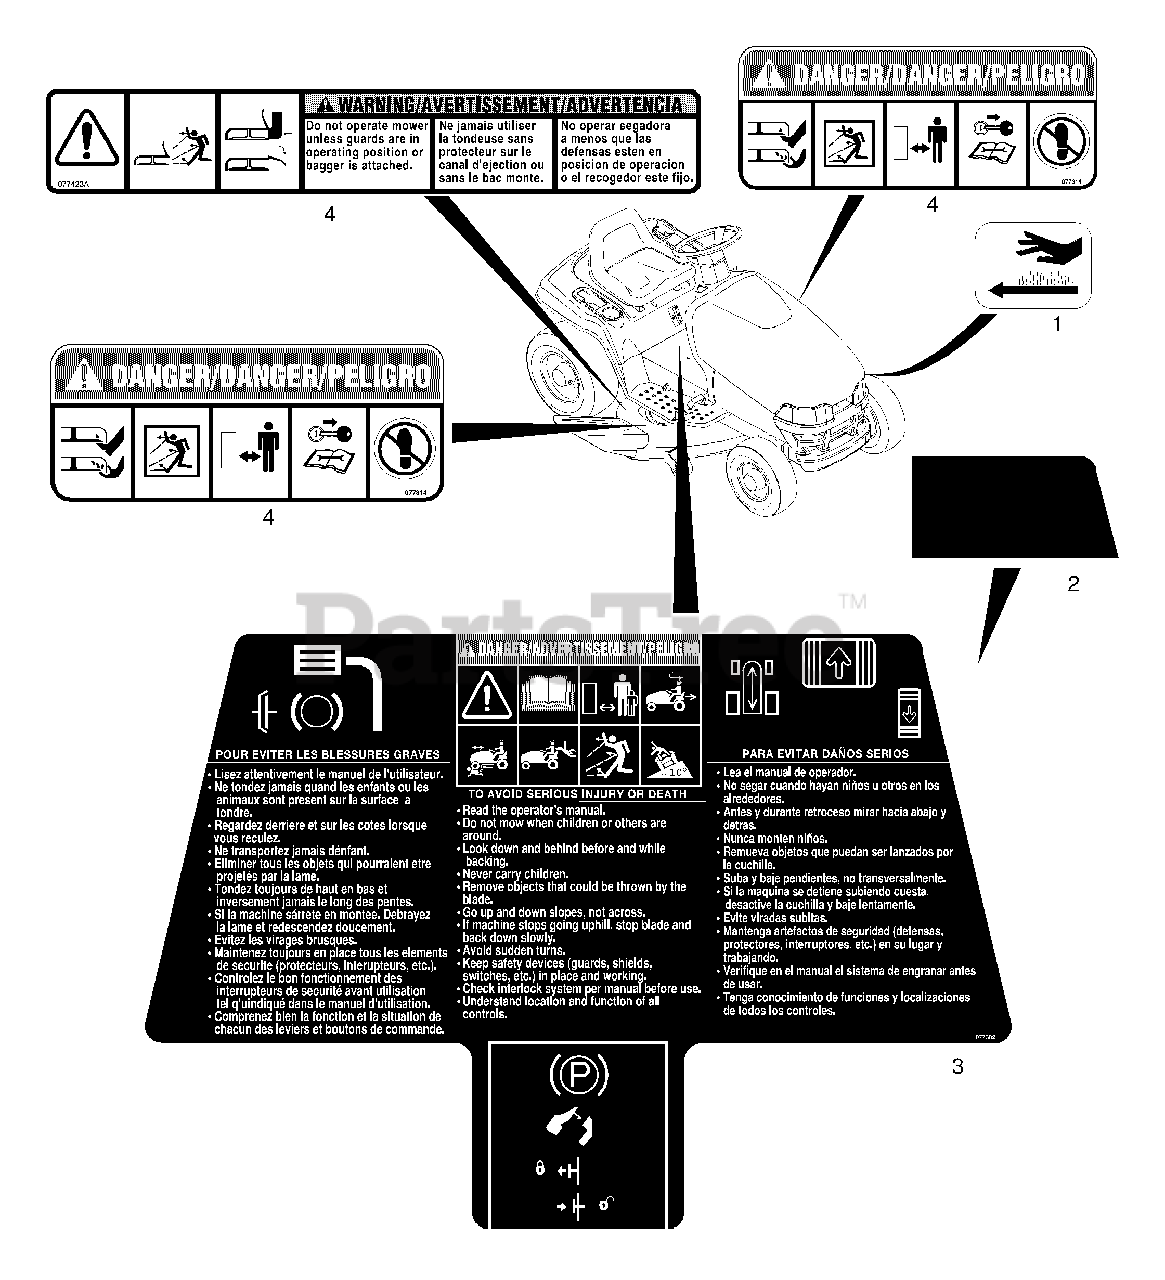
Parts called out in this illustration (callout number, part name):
1	DECAL- HOT SURFACE SYMB.
2	DECAL - COVER
3	DECAL OPERATING INSTRUCTIONS
4	DECAL SET - DECK
